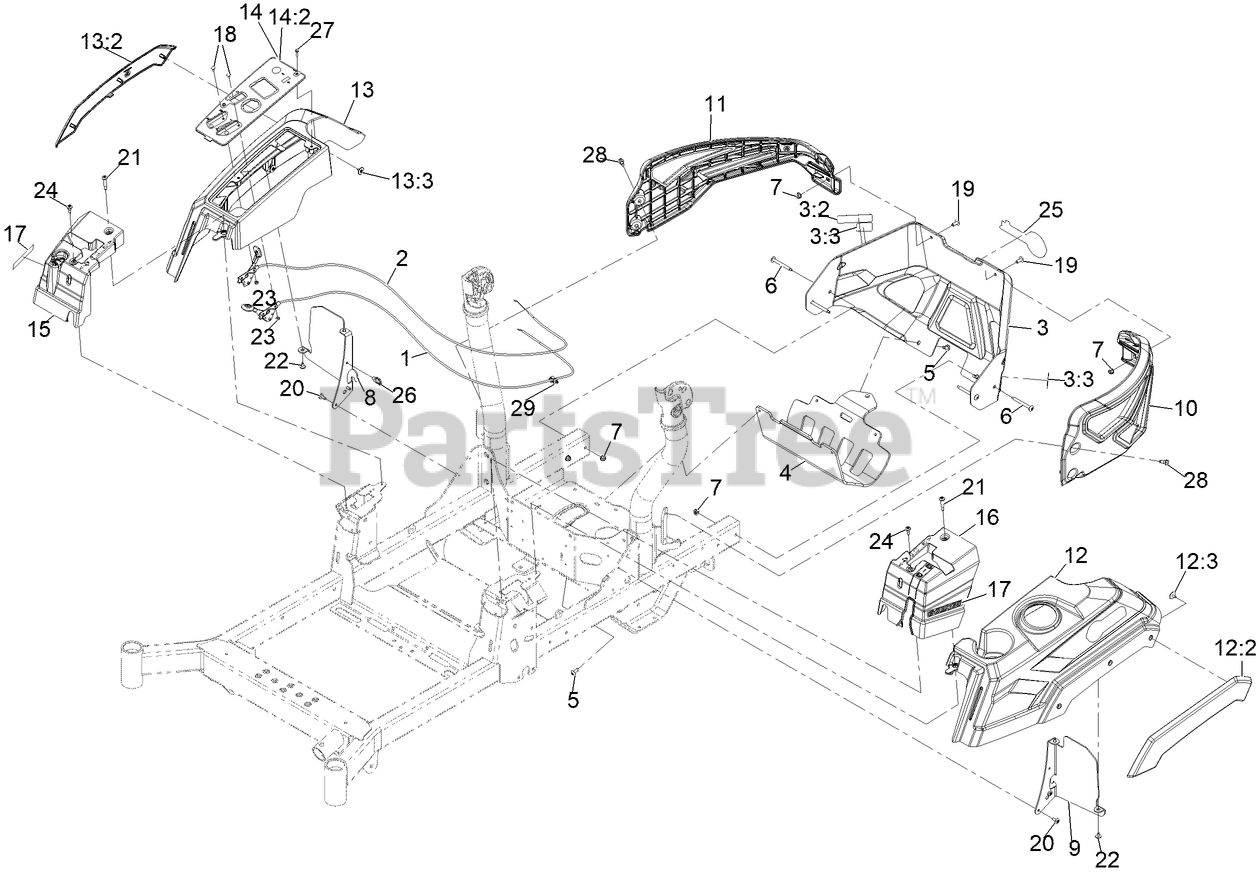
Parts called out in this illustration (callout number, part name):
1	CABLE-CONTROL, THROTTLE
2	CABLE-CONTROL, CHOKE
3	ASM, Rear Guard W/ Decals
3:2	DECAL-ARRESTOR, SPARK
3:3	DECAL-WARNING
4	Guard, Muffler
5	SCREW, TAPTITE
6	SCREW-TORX
7	NUT-HF, NI
8	Bracket, Pod, Rt
9	Bracket, Pod, Lt
10	GUARD, UPPER, LT
11	GUARD, UPPER, RT
12	ASM, Pod Lt
12:2	Fender, Lt
12:3	Screw-Torx
13	ASM, POD RT
13:2	Fender, Rt
13:3	Screw-Torx
14	ASM-Control Panel W/Decal
14:2	DECAL-CONTROL PANEL
15	Cover, Motion Control, Rt
16	Cover, Motion Control, Lt
17	DECAL-E-SERIES
18	BOLT-CARR
19	SCREW-TORX
20	SCREW-TORX
21	SCREW-SHOULDER
22	SCREW-TORX
23	NUT-LOCK, NI
24	SCREW-SHOULDER
25	DECAL, EXMARK LOGO
26	CLIP-TIE
27	Screw-Plastic, HWH
28	SCREW-SHOULDER
